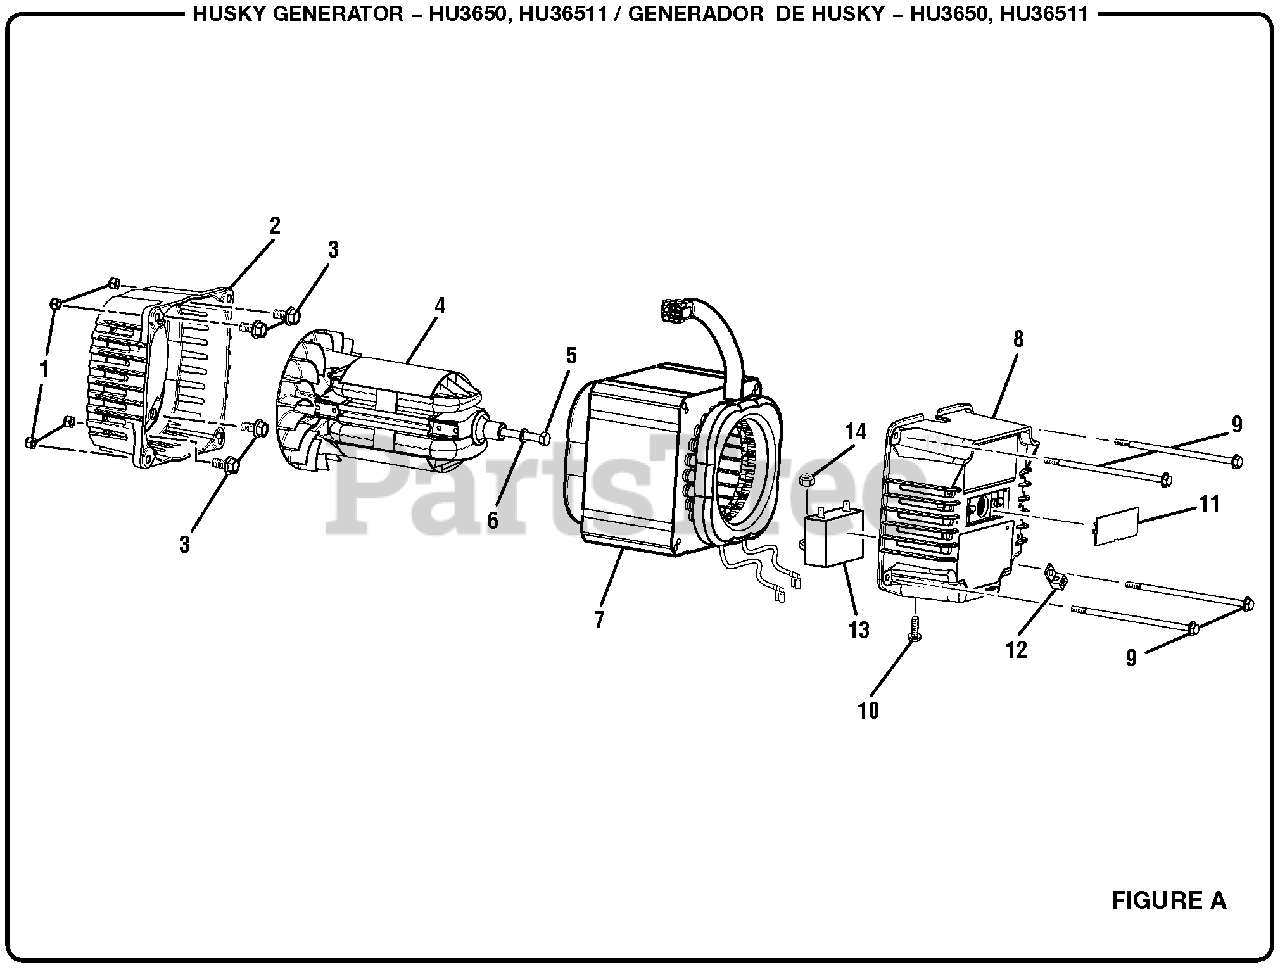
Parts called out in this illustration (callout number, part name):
1	Lock Nut (1/4-20)
2	Engine Adapter
3	Bolt (5/16-24 x 5/8 in.)
5	Bolt (5/16-24 x 7-3/4 in., Hex Hd.)
6	Lock Washer (5/16 in.)
9	Bolt (1/4-20 x 5-1/2 in. Hex Hd.)
10	Bolt (M5 x 16 mm, Pan Hd.)
11	Brush Cover
12	Ground Lug
13	Capacitor
14	Hex Nut (M5)
